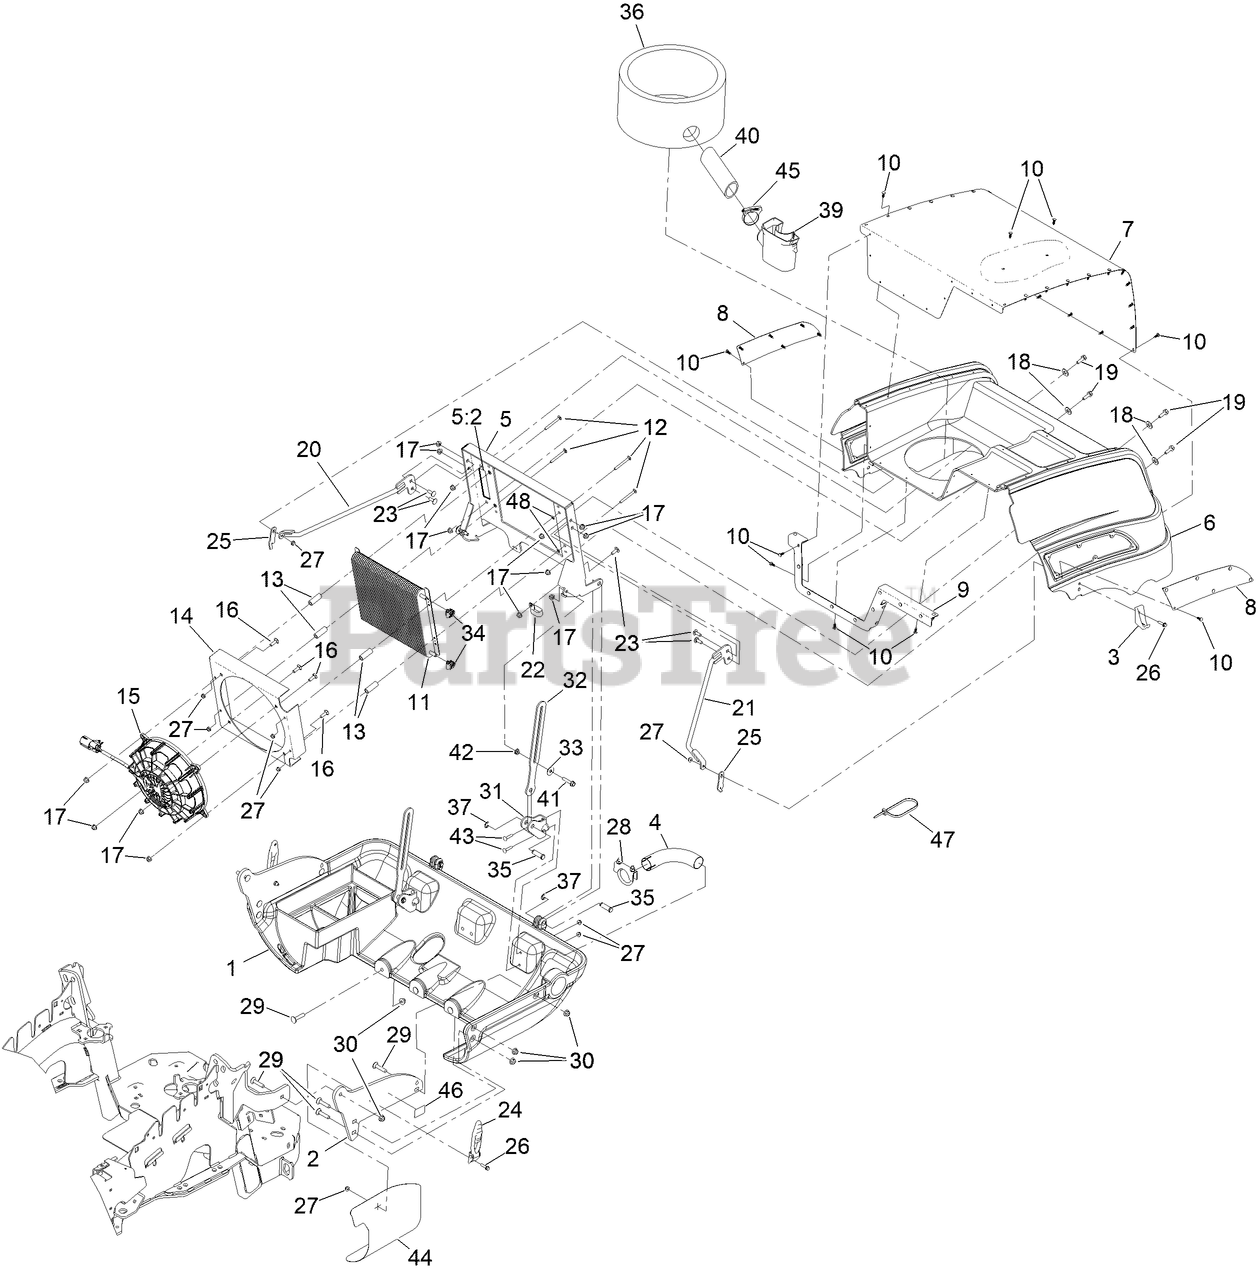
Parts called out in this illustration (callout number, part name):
1	CASTING-LOWER, REAR
2	PLATE-MOUNT
3	LATCH-CATCH
4	TUBE-EXHAUST
5	MOUNT-COOLER
5:2	DECAL-WARNING
7	SCREEN-INTAKE
8	SCREEN-INTAKE
9	CAP-PERFORATION, HOOD
10	PLUG-PLASTIC
11	COOLER-OIL
12	SCREW-CARR
13	SPACER
14	MOUNT-FAN
16	SCREW-CARR
17	NUT-HF, NI
18	WASHER-FLAT
19	SCREW-HHF
20	SUPPORT-HOOD, RH
21	SUPPORT-HOOD, LH
23	BOLT-CARR
24	LATCH-RUBBER
25	STOP-HOOD
26	SCREW-HHF
27	NUT-HF
28	CLAMP
29	SCREW-CARR
30	NUT-HF, NI
31	BRACKET-MOUNT, SLIDE
32	SLIDE-HOOD
33	WASHER-PLASTIC
34	CLAMP-HOSE
36	FOAM-INLET, AIR
37	RING-RETAINING, EXTERNAL
39	MOUNT-HOSE
40	HOSE-AIR INTAKE
41	SCREW-HHF
42	NUT-HF
43	SCREW-CARR
44	BARRIER-HEAT
46	DECAL-WARNING
47	TIE-CABLE
48	PUSHNUT-RETAINER, BOLT
